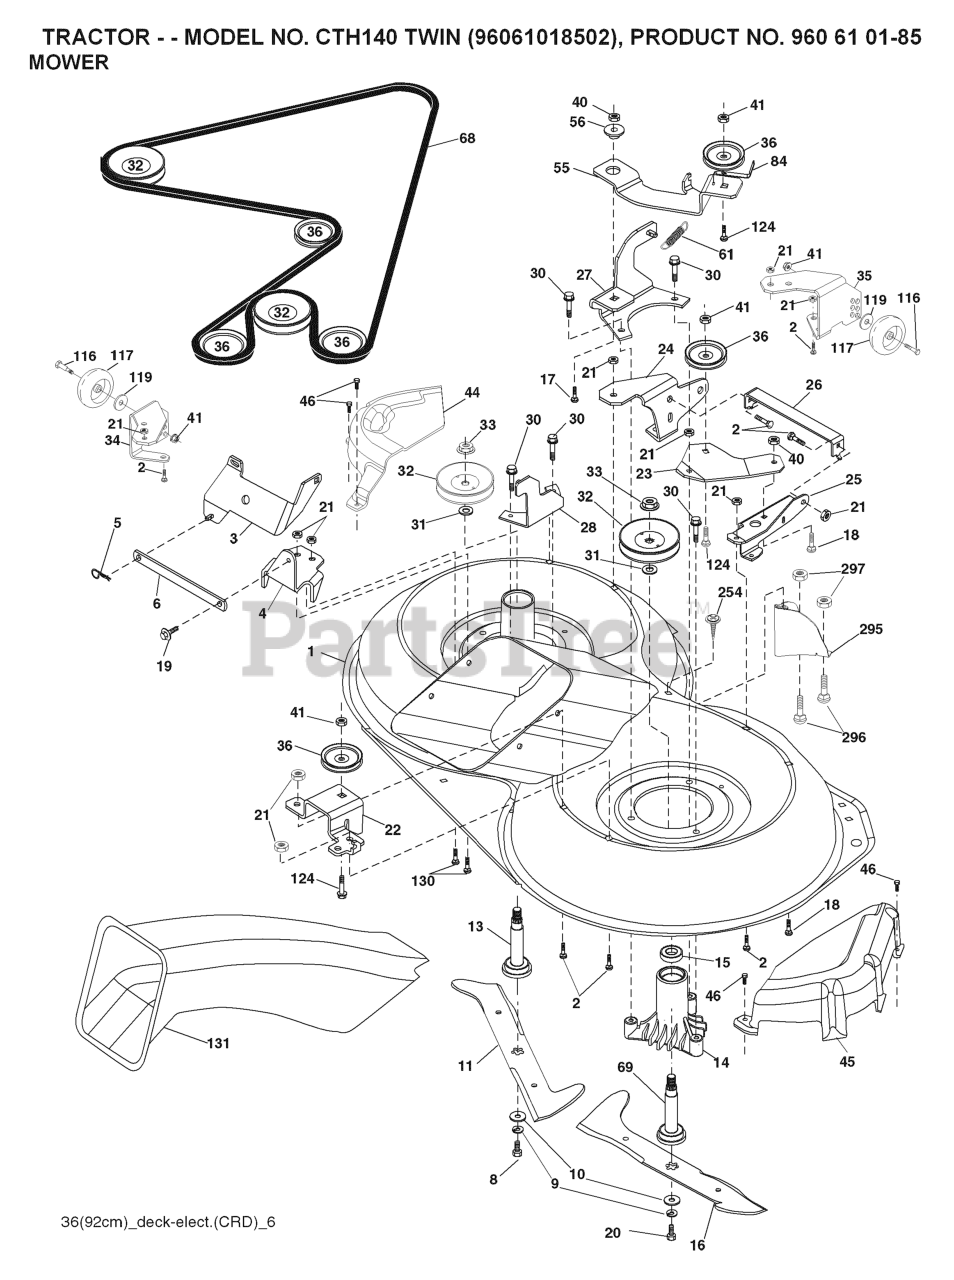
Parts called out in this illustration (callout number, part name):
2	RP BOLT 5/16-18 X3/4 ZN/YEL GR
5	RETAINER-SPRNG RB
6	BAR.SWAY.92.CRD
8	BOLT.3/8-24X1.25 GR8
9	LOCKWASHER
10	WASHER.BLADE
13	SHAFT ASM VENT
14	HOUSING.MANDREL.VENTED (MACHD)
17	BOLT.3/8-14X1.25
19	BOLT SHD 5/16-18
20	BOLT.3/8-24X1.25GR8. LHTHRD
21	LOCKNUT
26	SUPPORT
30	SCREW, WASHER HEAD
31	WASHER.SPACER.MANDREL
32	PULLEY, MANDREL
33	NUT.FLANGE.LOCK.TOP
36	PULLEY.IDLER.4.25
41	NUT LOCK FLG 3/8-16 UNC
45	COVER.MANDREL.RH.CRD
46	SCREW.1/4-20X5/8
55	ARM.IDLER.92 CRD.2006
56	SPACER.RETAINER.MOWER
61	SPRING.TENSION.BELT
68	BELT.DRIVE.92CM.CRD.2006
69	SHAFT.ASM.W/LWR.BRG.RH.THREAD
84	KEEPER, BELT IDLER
116	BOLT.SHOULDER.3/8-16X3-5/8.
117	RP WHEEL. GUAGE RALLY
118	NUT LOCK FLG 3/8-16 UNC
119	WASHER
124	BOLT.3/8-16X1.50
130	BOLT.CARR.SQNK.5/16-18UNC.X3/4
131	CHUTE BAGGER
254	SCREW 3/8-16X1
296	BOLT
297	NUT CENTERLOCK
